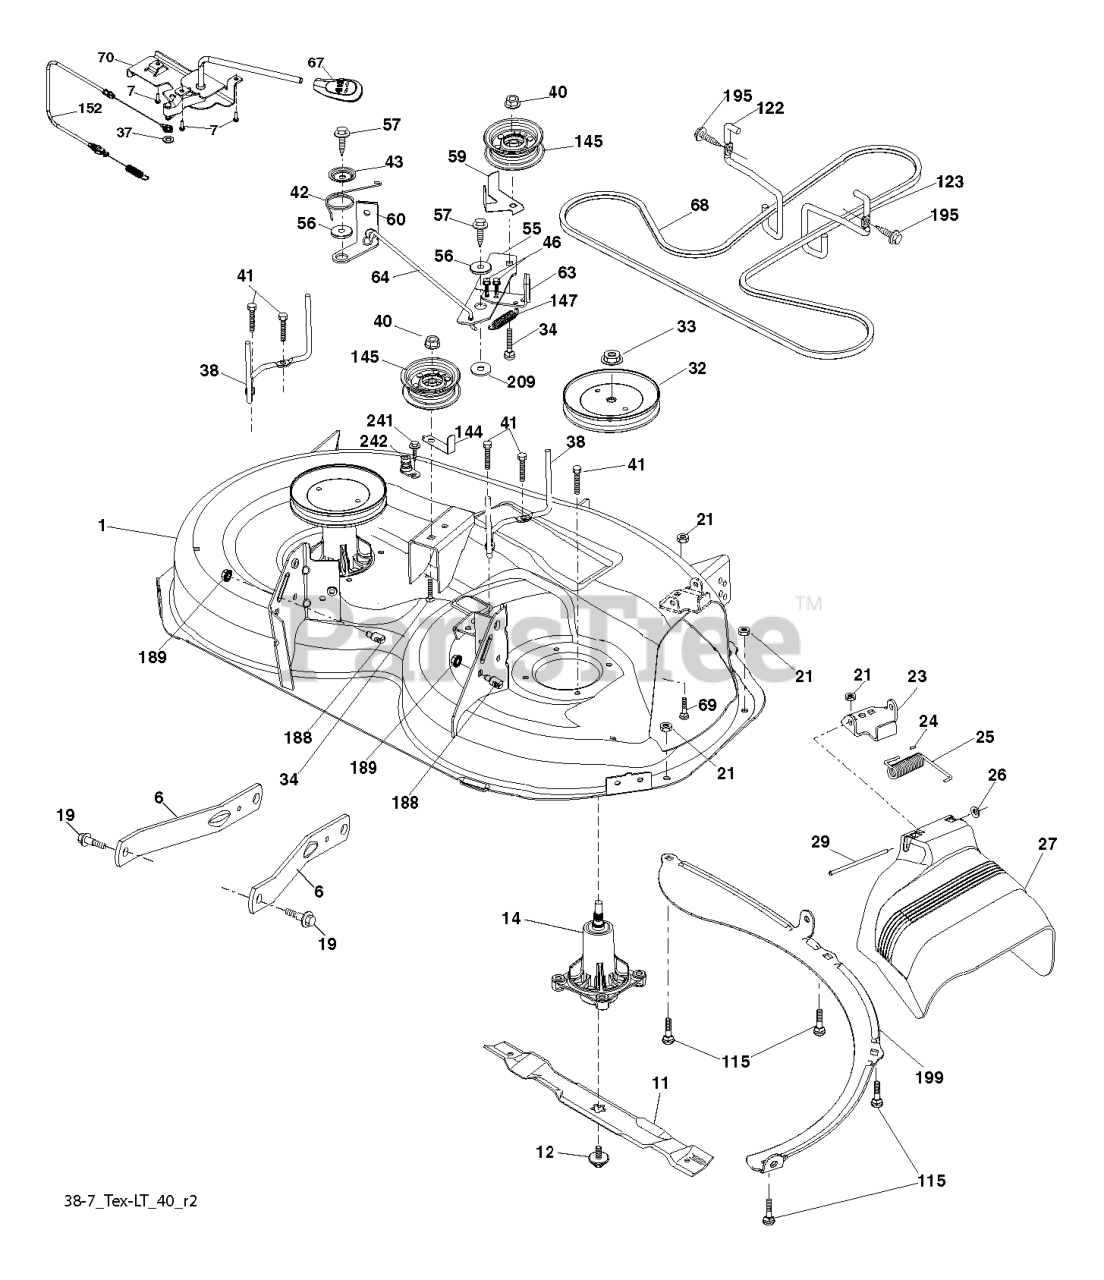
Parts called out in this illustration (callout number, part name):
6	ARM.SUSPENSION.MOWER.R
11	BLADE.2 IN 1.38"DECK.BLACK
12	SCREW.SEMS.7/16-20X1.HEX.HEAD
14	KIT.MANDREL.NONGREASE.TALL
19	BOLT.SHOULDER
23	BRKT.DEFLECTOR.38"2005+
24	CAP-SLEEVE LT
25	SPRING.TORSION.DEFLECT
26	NUT PUSH M
27	SHIELD, DEFLECTOR
32	PULLEY.MANDREL.5.0.PD.38"
34	GSPW Bolts
37	WASHER PLAIN WASHER 3/8 X 0.08
38	KEEPER BELT LH MANDREL
40	NUT LOCK FLG 3/8-16 UNC
41	BOLT.HEX.WASHR.HED.313-18X1.19
42	SPRING.TORSION.BRAKE
43	SRPING.TORSION.RETAINE
46	SCREW.1/4-20X5/8
56	SPACER.RETAINER
57	SCREW 3/8-16X1
59	GUARD, BELT
60	ARM BRAKE MOWER RH 38"
63	RP ARM.BRAKE.MOWER.38"LH.TEX
64	LINK BRAKE
67	HANDLE.CLUTCH.CABLE.LT
70	CLUTCH.ASM.MANUAL.LT.PRED
115	BOLT ROUND HEAD SQUARE NECK BO
122	KEEPER BELT ENGINE LH
123	KEEPER BELT RH
144	KEEPER BELT
145	PULLEY.IDLER.48"PRIMARY
147	SPRING RETURN
152	CABLE.CLUTCH.MANUAL.
188	STUD.W/"D"ANTI-ROTATION
195	SCREW, 3/8-16X3/4
199	BAFFLE.VORTEX.FRONT.38"
241	SCREW.TT.#10-32X.5.3/8.FLANGE
242	PORT.WASHOUT
